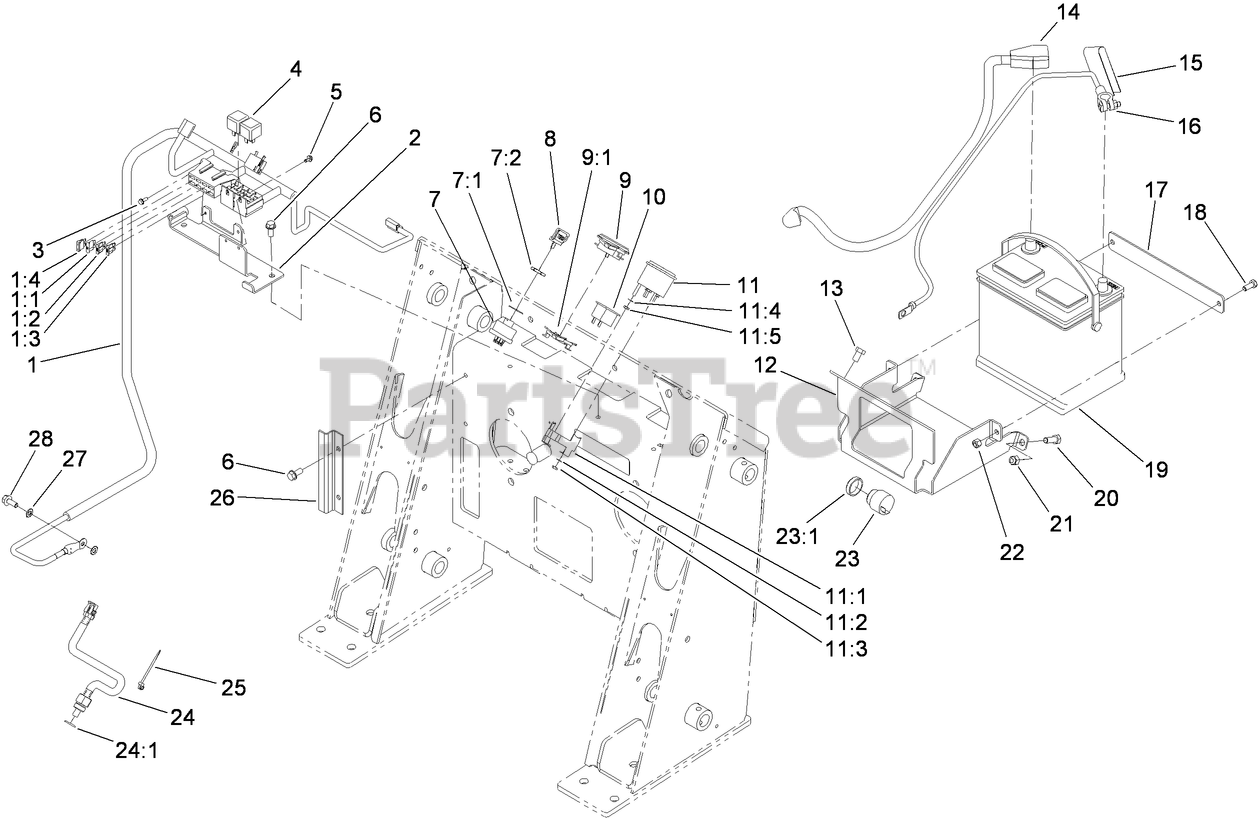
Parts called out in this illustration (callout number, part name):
1	HARNESS-WIRE
1:1	FUSE-BLADE, 10 AMP
1:2	FUSE-BLADE, 25 AMP
1:3	FUSE-BLADE, 30 AMP
1:4	FUSE-BLADE, 15 AMP
2	Fuse/Relay Bracket ASM
3	SCREW-HWH
4	RELAY
5	SCREW-HWH
6	SCREW-HWHTF
7	Key Switch ASM
7:1	WASHER-TOOTH, INTERNAL
7:2	NUT-HH
8	KEY-IGNITION
9	INDUCTIVE HOURMETER ASM
9:1	CLIP-MOUNTING
10	LIGHT-TEMP, OIL
11	GAUGE-FUEL
11:1	BRACKET-MOUNTING, GAUGE
11:2	WASHER-LOCK, INT
11:3	NUT-HEX
11:4	WASHER-LOCK / EXT
11:5	NUT-HEX
12	TRAY-MOUNTING, BATTERY
13	SCREW-HWHTF
14	CABLE-BATTERY, POSITIVE
15	DECAL-INSTRUCTIONS, CHARGING
16	CABLE-BATTERY, NEGATIVE
17	CLAMP-BATTERY
18	SCREW-HH
19	BATTERY
20	SCREW-HH
21	NUT-LOCK, NI
22	NUT-LOCK, NI
23	AUDIO ALARM ASM
23:1	NUT-PLASTIC, KNURLED
24	SENSOR-TEMPERATURE
24:1	O-RING
25	TIE-CABLE
26	SHIELD-WIRING
27	WASHER-LOCK
28	SCREW-HHF
